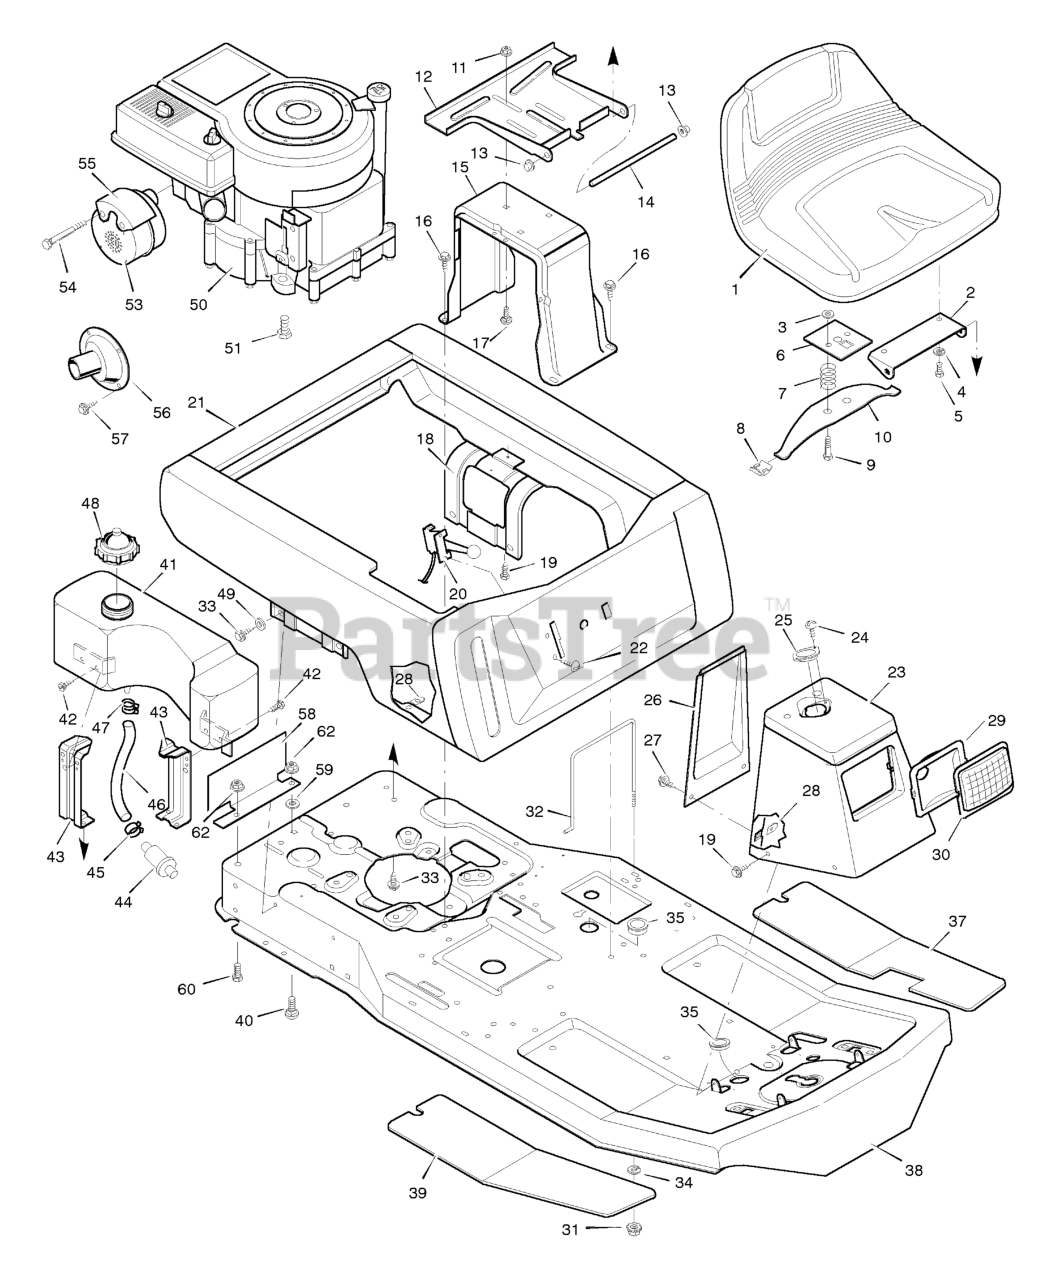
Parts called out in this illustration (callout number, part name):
2	Hinge, Seat
3	Retainer
4	Lockwasher
5	Bolt, Hex
6	Plate, Seat Switch
7	Spring, Compression
8	Glide, Seat Spring
9	Bolt, Shoulder
10	Spring, Seat
11	Locknut, Flange
12	Bracket, Seat Pivot
13	Cap, Push On
14	Rod, Seat Hinge
15	Support, Seat
17	Bolt, Carriage
18	Support, Body
20	Throttle Control
23	Console Assembly
25	Bearing, Steering Post
26	Console, Plate
28	J- Nut
29	Reflector
31	Locknut
32	Clamp, Battery
35	Grommet
37	Mat, Left
38	Frame Assembly
39	Mat, Right
40	Bolt, Carriage
41	Tank, Fuel
43	Bracket, Fuel Tank
44	Filter, Fuel
46	Line, Fuel
47	Clamp
48	Cap, Fuel
49	Washer
50	Engine *
51	Bolt, Engine Mount
53	Muffler
55	Shield, Heat
56	Deflector, Exhaust
58	Shield, Heat
59	Washer
60	Bolt
62	Locknut, Flange
